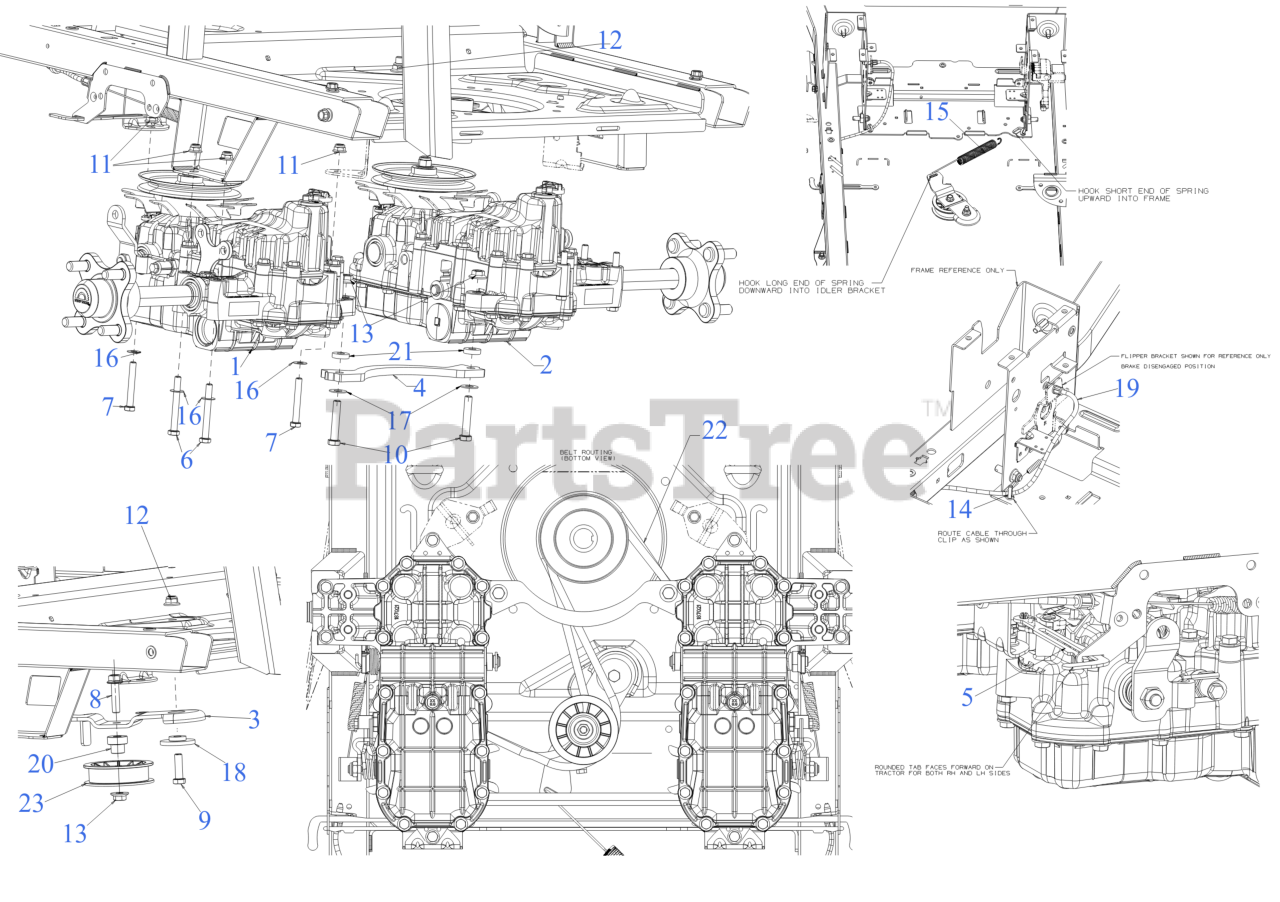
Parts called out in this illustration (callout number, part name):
1	HYDRO TRANSMISSION (LH)
2	HYDRO TRANSMISSION (RH)
3	HYDRO DRIVE IDLER BRACKET
4	TRANSMISSION BRACKET
5	TRANSMISSION BYPASS PLATE
6	HEX SCREW 5/16-18 x 2.75
7	HEX SCREW 5/16-18 x 2.25 GR5
8	HEX HEAD BOLT (3/8-16:1.50 GR8)
9	SCREW 3/8-16 x 1.25 GR5
10	SCREW 3/8-16 x 2.0 GR 8
11	FLANGE LOCK NUT 5/16-18
13	FLANGE LOCK NUT
14	CABLE RETAINER CLIP
15	EXTENSION SPRING .75 DIA X 10.27
16	FLAT WASHER
17	FLAT WASHER .401X.88
18	SHOULDER SPACER
19	PARK BRAKE CABLE
20	SHOULDER SPACER
22	TRANSMISSION DRIVE BELT A x 67
23	FLAT IDLER PULLEY 3.00 OD
